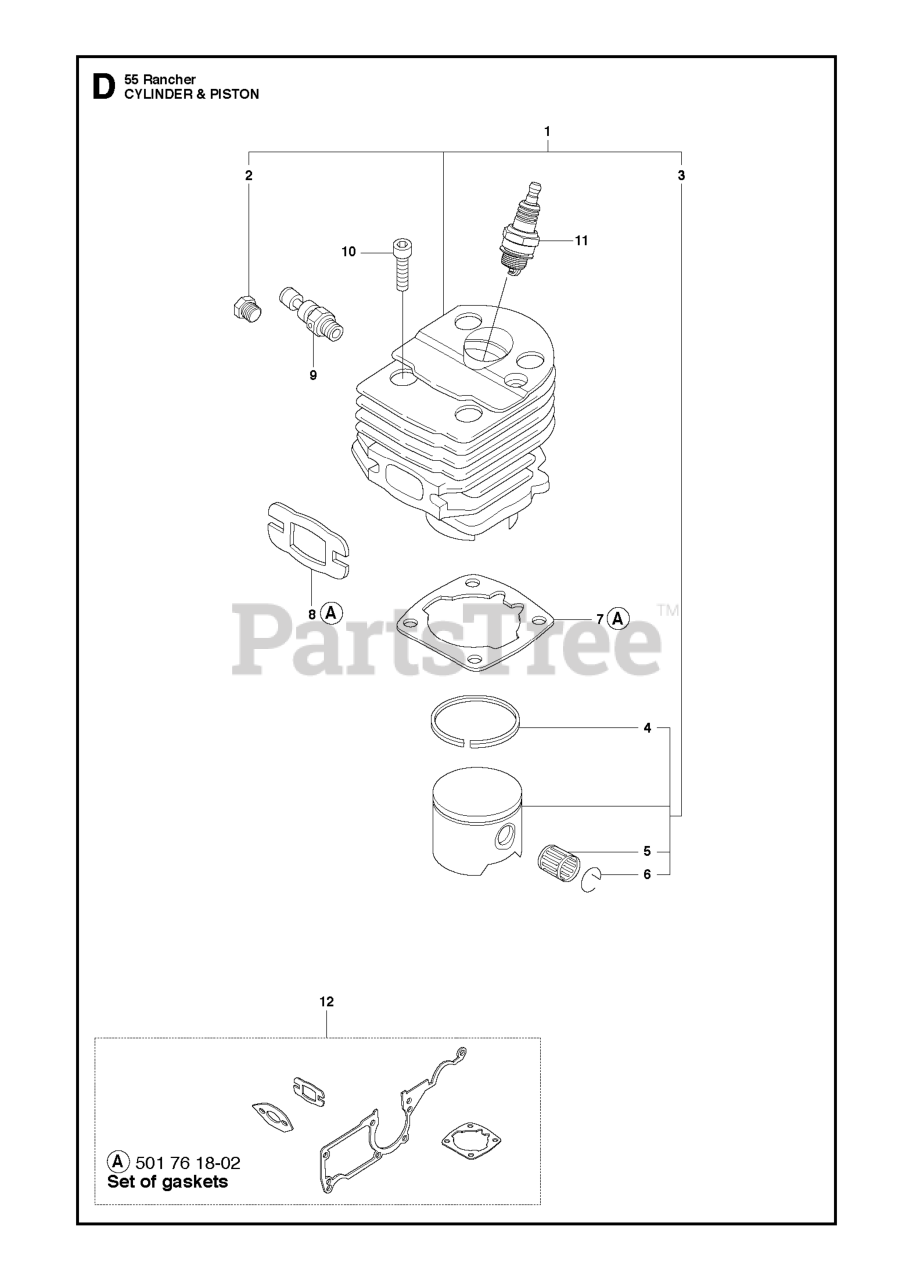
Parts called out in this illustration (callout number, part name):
1	CYLINDER ASSY
2	CYLINDER PLUG
3	PISTON ASSEMBLY
4	PISTON RING
5	SUPPORT BUSHING
6	LOCKING RING
9	DECOMPRESSION VALVE
11	SPARK PLUG RCJ7Y
12	GASKET SET
